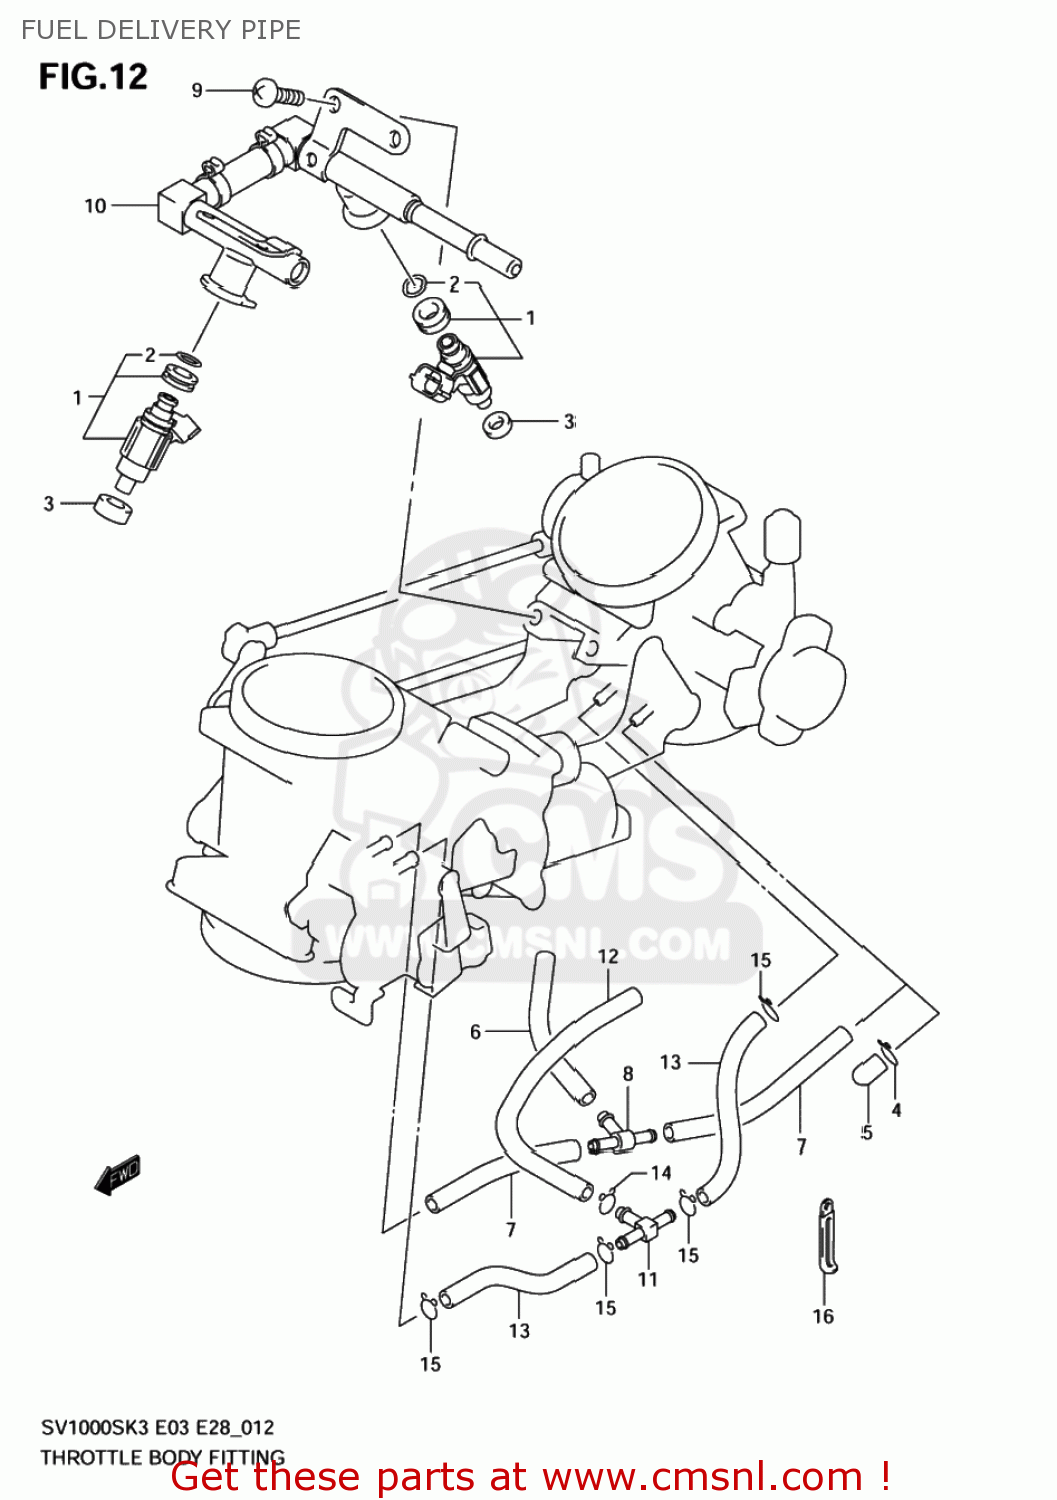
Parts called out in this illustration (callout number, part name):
1	INJECTOR ASSY
2	O RING
3	CUSHION,FUEL INJECTOR
4	CLIP
5	CAP
6	HOSE(3.2X7.4X225)
7	HOSE(3.2X7.4X225)
8	3WAY,VACUUM HOSE
9	SCREW
10	DELIVERY PIPE ASSY
11	NIPPLE
12	HOSE
13	HOSE(3.2X7.4X225)
14	CLIP
15	CLIP
16	CLAMP(L:45)
